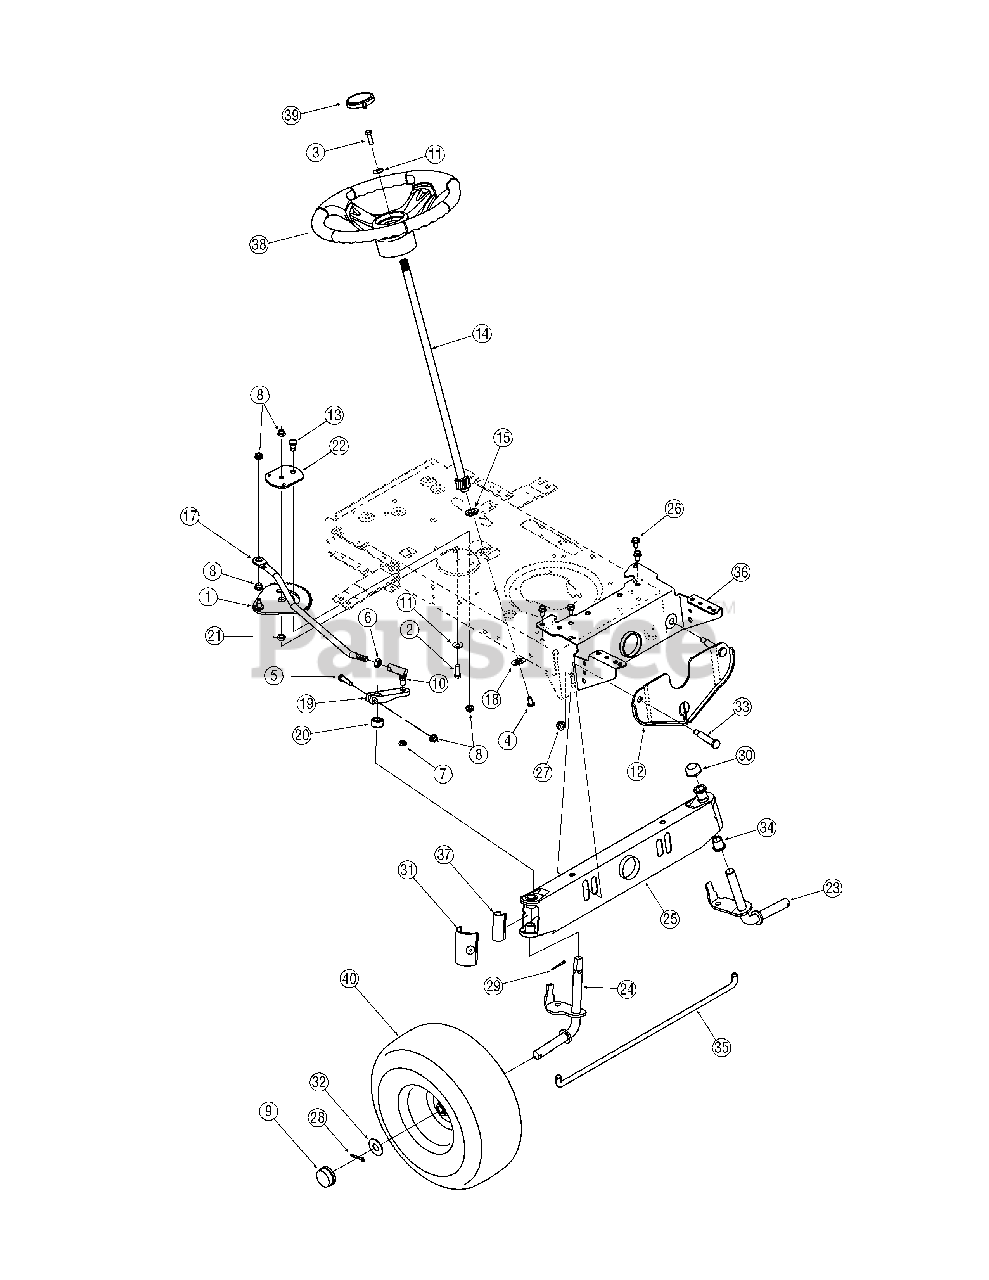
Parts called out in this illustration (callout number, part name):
1	Gear Assembly, Steering
2	Screw, 5/16-18, 1.00, Gr5
3	Screw, 5/16-18, 1.00, Gr5, Lock
4	Screw, Mach, 5/16-18, 0.750
5	Screw, 5/16-18, 1.75, Gr5
6	Nut, Jam, 7/16-20, Gr2
7	Nut, Jam Lock, 3/8-24, Gr2
8	Nut, Flange Lock, 5/16-18, Grf, Nylon
9	Hub Cap
10	Ball Joint, 7/16-20, Lock
11	Washer, Bell, .340 x .872 x .060
13	Screw, Shoulder, .435 x .3485, 5/16-18
14	Steering Shaft, 5/8 Spline x 21.86
15	Bearing, Flange, Hex 5/8
16	Plastic Bushing .380 ID
17	Drag Link, Steering"
18	Cap, 1.25 x .16"
20	Spacer, .710 ID x .125 OD x .56"
21	Spacer, .322 ID x .625 OD x .21"
22	Stabilizer Plate, Gear Segment"
26	Screw, 5/16-12, 0.750"
27	Nut, Flange Lock, 3/8-16, GrF, Nylon"
28	Pin, Cotter, 5/32, 1.25"
29	Pin, Cotter, 1/8 x 1.25"
30	Push Cap, 3/4"
31	End Cap, Pivot Bar (w/ Fitting)"
32	Washer, Flat, .78 x 1.59 x .060"
33	Screw, Shoulder, .500 x 2.380, 3/8-16"
34	Bearing, Flange, .760 x .941 x 1.0"
35	Tie Rod
37	Axle End Cap, Standard"
38	Steering Wheel, Standard Grip"
38	Steering Wheel, Soft Grip"
39	Cap, Steering Wheel (no logo)"
39	Cap, Steering Wheel (sprig logo)"
39	Cap, Steering Wheel (tine logo)"
